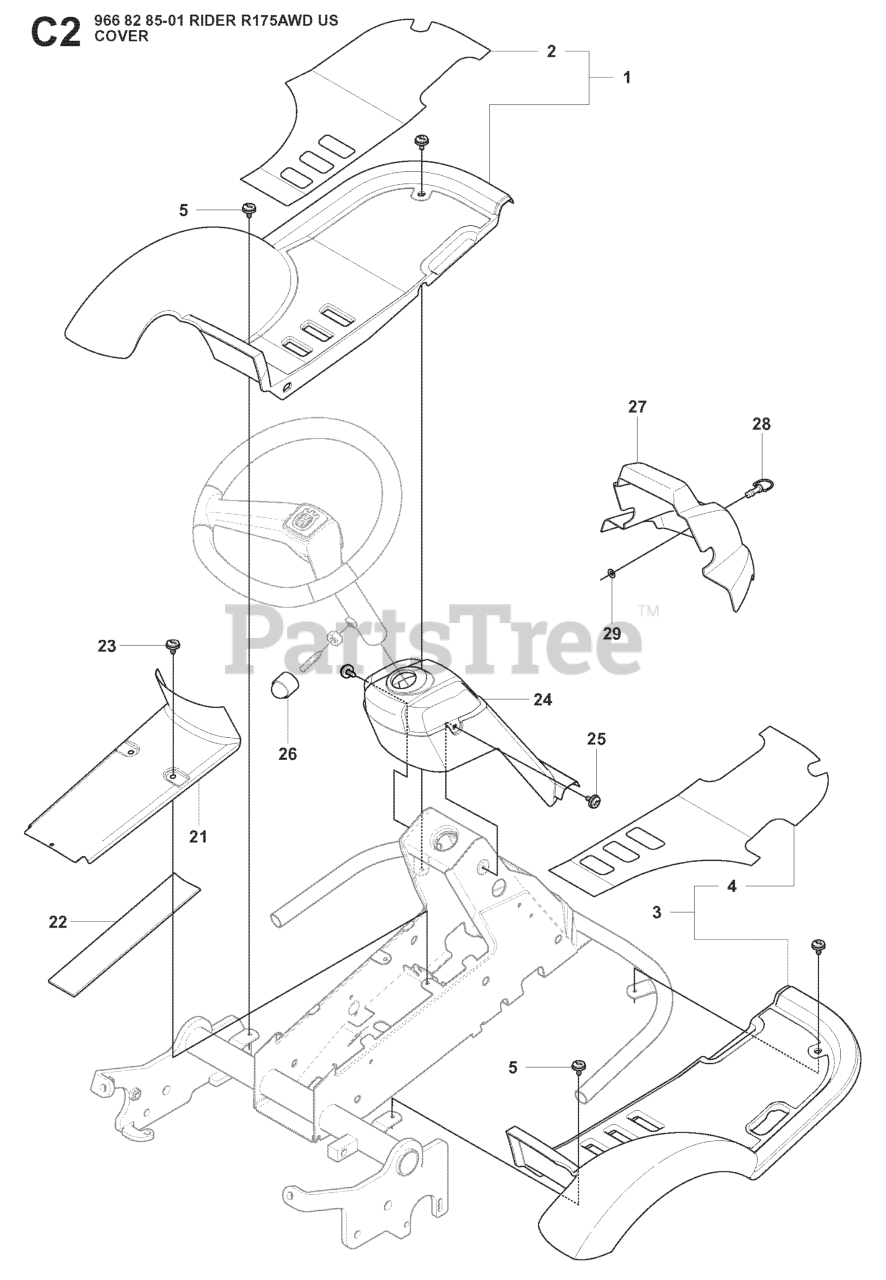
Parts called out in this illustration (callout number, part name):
1	FOOT PLATE
3	FOOT PLATE
26	PROTECTIVE COVER
28	BOLT
